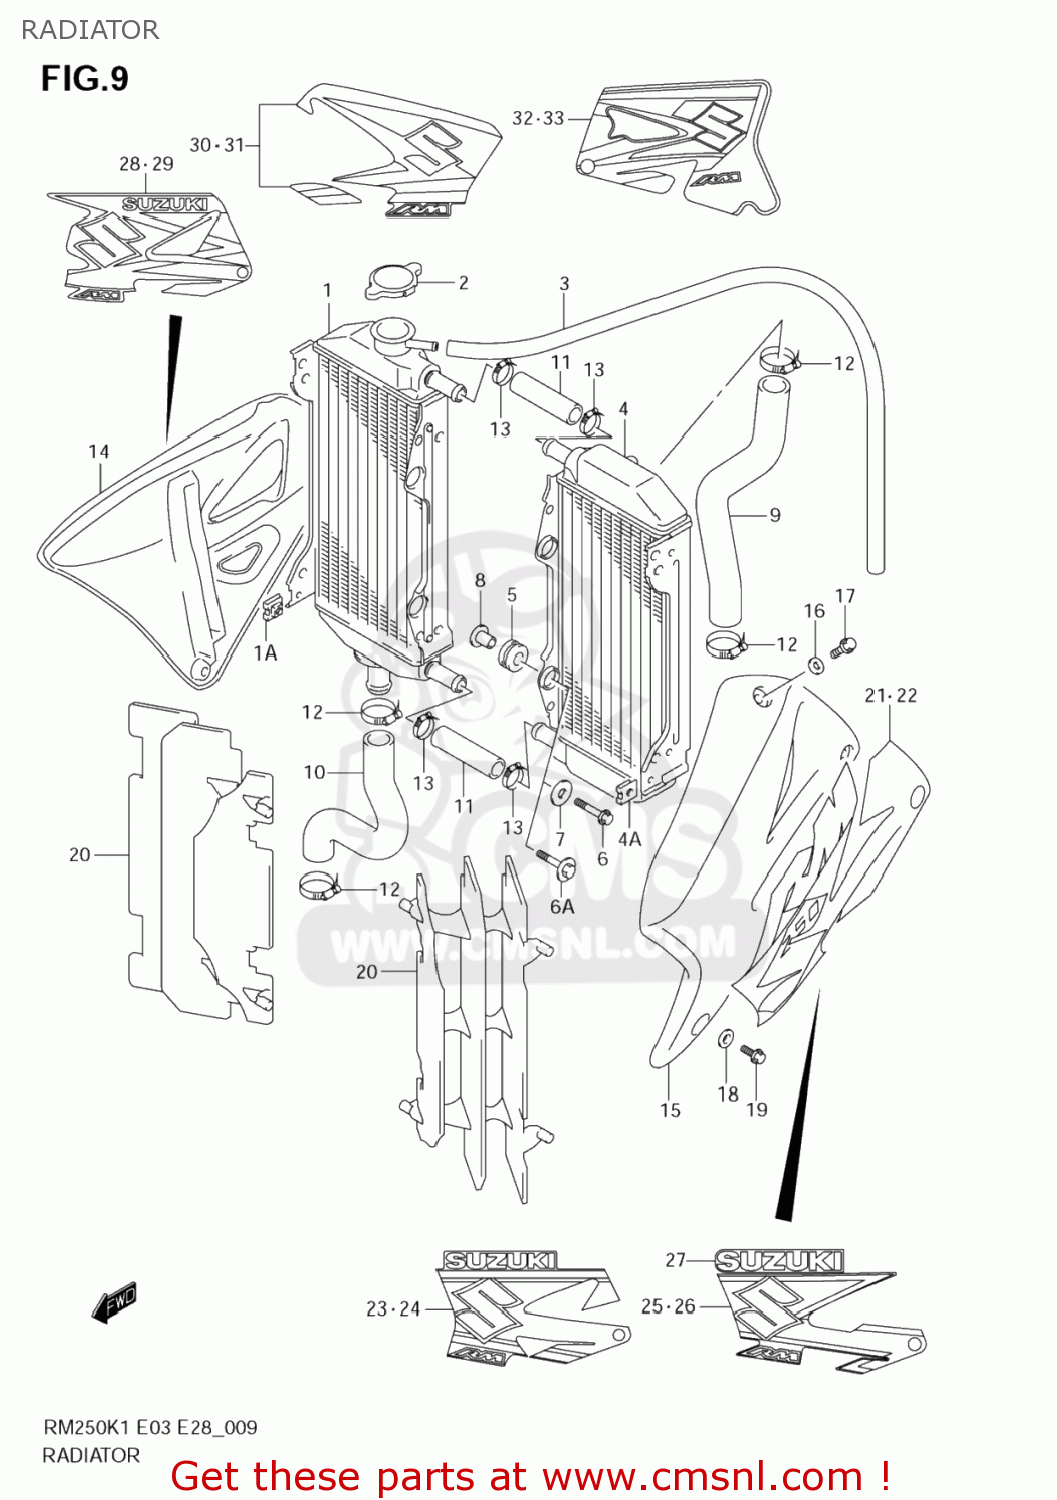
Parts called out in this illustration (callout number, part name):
1	RADIATOR,WATER,R
1A	NUT
2	CAP COMP,RADIATOR
3	HOSE(5X8X1000)
4	RADIATOR,WATER,L
4A	NUT
5	CUSHION,RADIATOR LWR
6	SCREW
6A	BOLT(6X25)
7	WASHER(6.5X24X1.2)
8	SPACER(6.5X10.5X14.1)
9	HOSE,RADIATOR INLET
10	HOSE,RADIATOR OUTLET
11	HOSE,RADIATOR
12	CLAMP
13	CLAMP
14	COVER,RDTR,R
15	COVER,RDTR,L
16	WASHER
17	SCREW
18	WASHER
19	BOLT
20	LOUVER,RADIATOR
21	TAPE, RADIATOR COVER RH
22	TAPE, RADIATOR COVER LH
23	TAPE,RADIATOR COVER,R
24	TAPE,RADIATOR COVER,L
25	TAPE, RADIATOR COVER RH
26	TAPE,RADIATOR COVER,L
27	EMBLEM,SUZUKI
28	TAPE,RADIATOR COVER,R
29	TAPE,RADIATOR COVER,L
30	TAPE,RADIATOR COVER,R
31	TAPE, RADIATOR COVER LH
32	TAPE, RADIATOR COVER RH
33	TAPE, RADIATOR COVER LH
